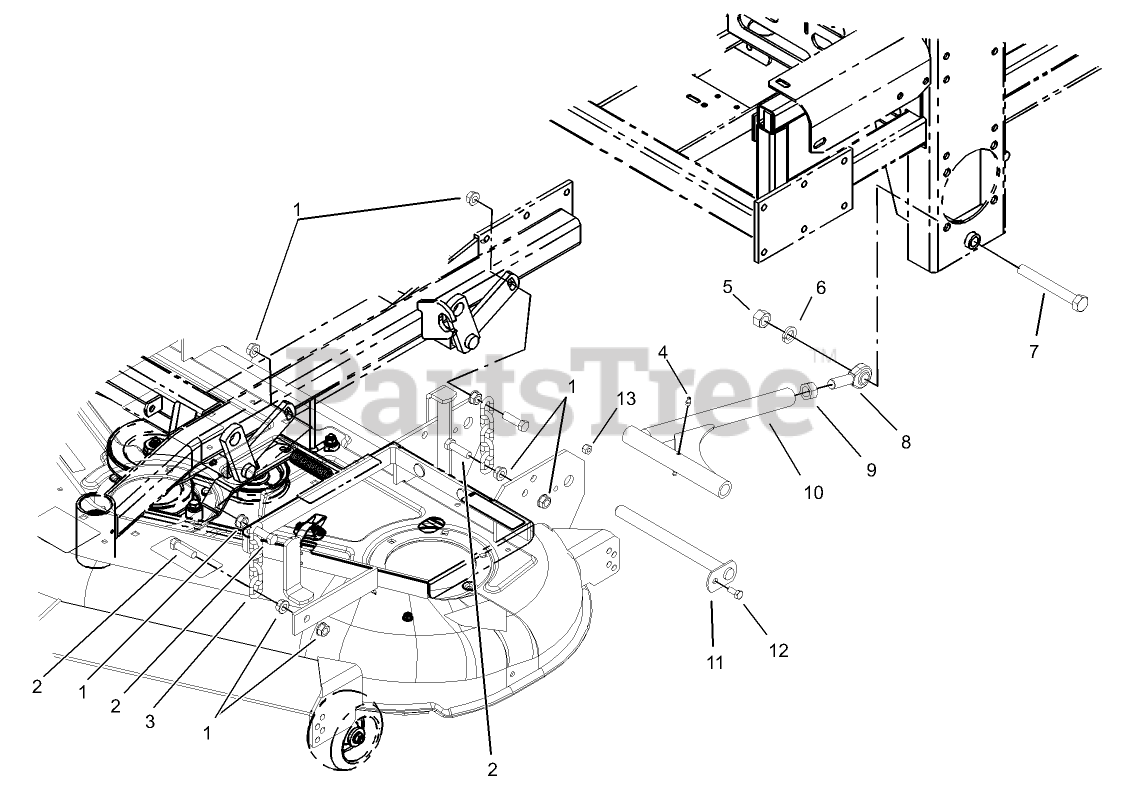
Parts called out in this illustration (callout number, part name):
1	NUT-HF
2	SCREW-CAP, HH
3	CHAIN-LIFT, DECK
4	FITTING-GREASE
5	NUT-HEX
6	WASHER-LOCK
7	SCREW-HH
8	BALLJOINT-SPHERICAL
9	NUT-HEX
10	STRUT
11	PIN-STRUT
12	SCREW-HH
13	NUT-LOCK, NI
